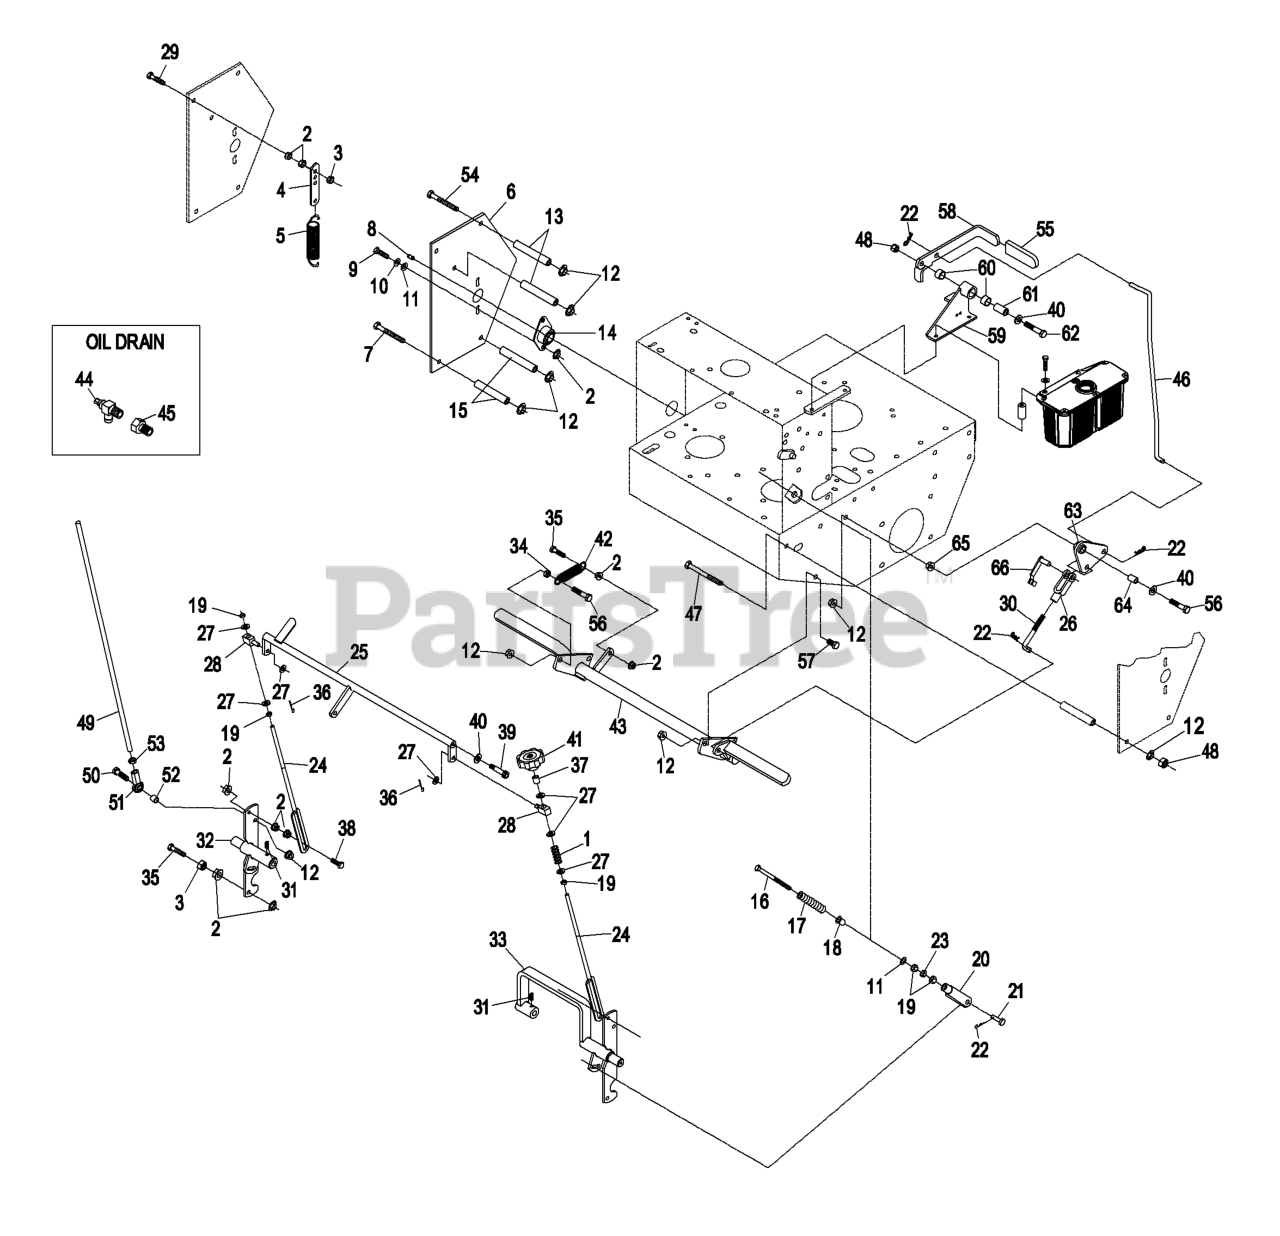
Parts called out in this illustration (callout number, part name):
1	SPRING-COMPRESSION
3	NUT-LOCK, NI
4	TAB-SPRING, EXTENSION
5	SPRING-EXTENSION
7	SCREW-HH
8	FITTING-GREASE
9	SCREW-HH
10	WASHER-LOCK
11	WASHER-FLAT
12	NUT-HHF, WHIZ
13	SPACER-SHIELD
14	BEARING-FLANGE, SIDE
15	SPACER-SHIELD
16	BOLT-RETURN, NEUTRAL
17	SPRING,COMPRESSION (NEUT)
18	BUSHING-FLANGED
19	NUT-HEX
20	YOKE-ADJUSTABLE
21	PIN-CLEVIS
22	PIN-COTTER
23	NUT-JAM
24	LINK-CONTROL, SPEED
26	YOKE-LINKAGE, BRAKE
27	WASHER-PLAIN
29	BOLT-TAP, HH
30	LINKAGE-LOWER
31	SCREW-SET
32	SHAFT-CONTROL, LH
34	NUT-JAM
35	SCREW-HH
36	PIN-COTTER
38	SCREW-HH
39	SCREW-HSH
40	WASHER-FLAT
41	KNOB-TRACKING
42	SPRING-IDLER
44	VALVE-DRAIN, OIL
45	ADAPTER
46	LINKAGE,UPPER- TTHP
47	SCREW-HH
48	NUT-LOCK, NI
49	LINK,DRIVE (PLTD)
50	SCREW-HH
51	JOINT-BALL END, LH
52	SPACER-TUBE, PUMP LINK
53	NUT-HEX JAM, LH
54	SCREW-HH
55	GRIP-LEVER
56	SCREW-HH
57	SCREW-HH
59	BRACKET ASM
60	SLEEVE-BUSHING
61	BUSHING-PIVOT
62	SCREW-HH
63	BELLCRANK ASM
64	BUSHING-PLASTIC
66	PIN-SPRING, CLEVIS
